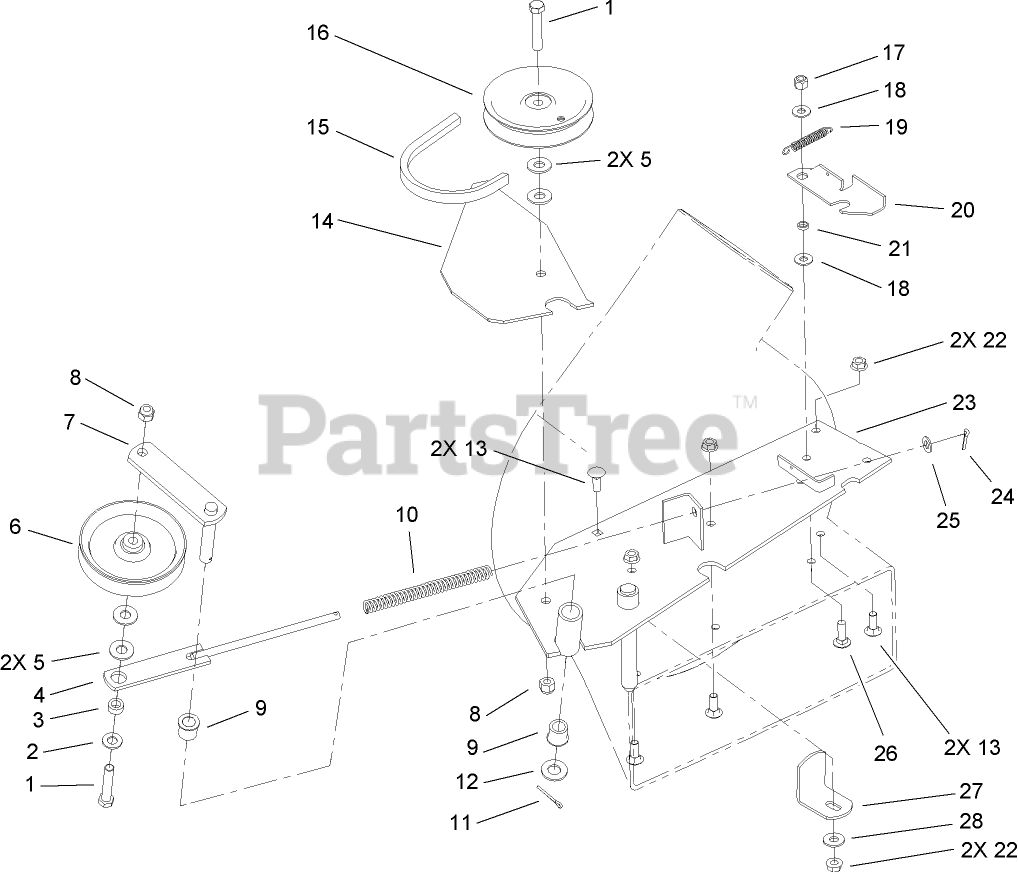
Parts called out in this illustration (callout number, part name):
1	SCREW-HH
2	WASHER-FLAT
3	SPACER
4	SPRING-ROD
5	WASHER-FLAT
6	PULLEY-IDLER
7	IDLER ARM ASM
8	NUT-LOCK, NI
9	BUSHING
10	SPRING-COMPRESSION
11	PIN-COTTER
12	WASHER-FLAT
13	SCREW-CARR
14	SUPPORT-SHIELD, BELT
15	BELT-V
16	PULLEY-IDLER
17	NUT-LOCK, NI
18	WASHER-FLAT
19	SPRING-EXTENSION
20	LATCH-BLOWER
21	BUSHING
22	NUT-HF
23	MOUNTING-BLOWER
24	PIN-COTTER
25	WASHER-PLAIN
26	BOLT-CARR
27	BRACKET-SUPPORT, HOUSING
28	WASHER-FLAT
